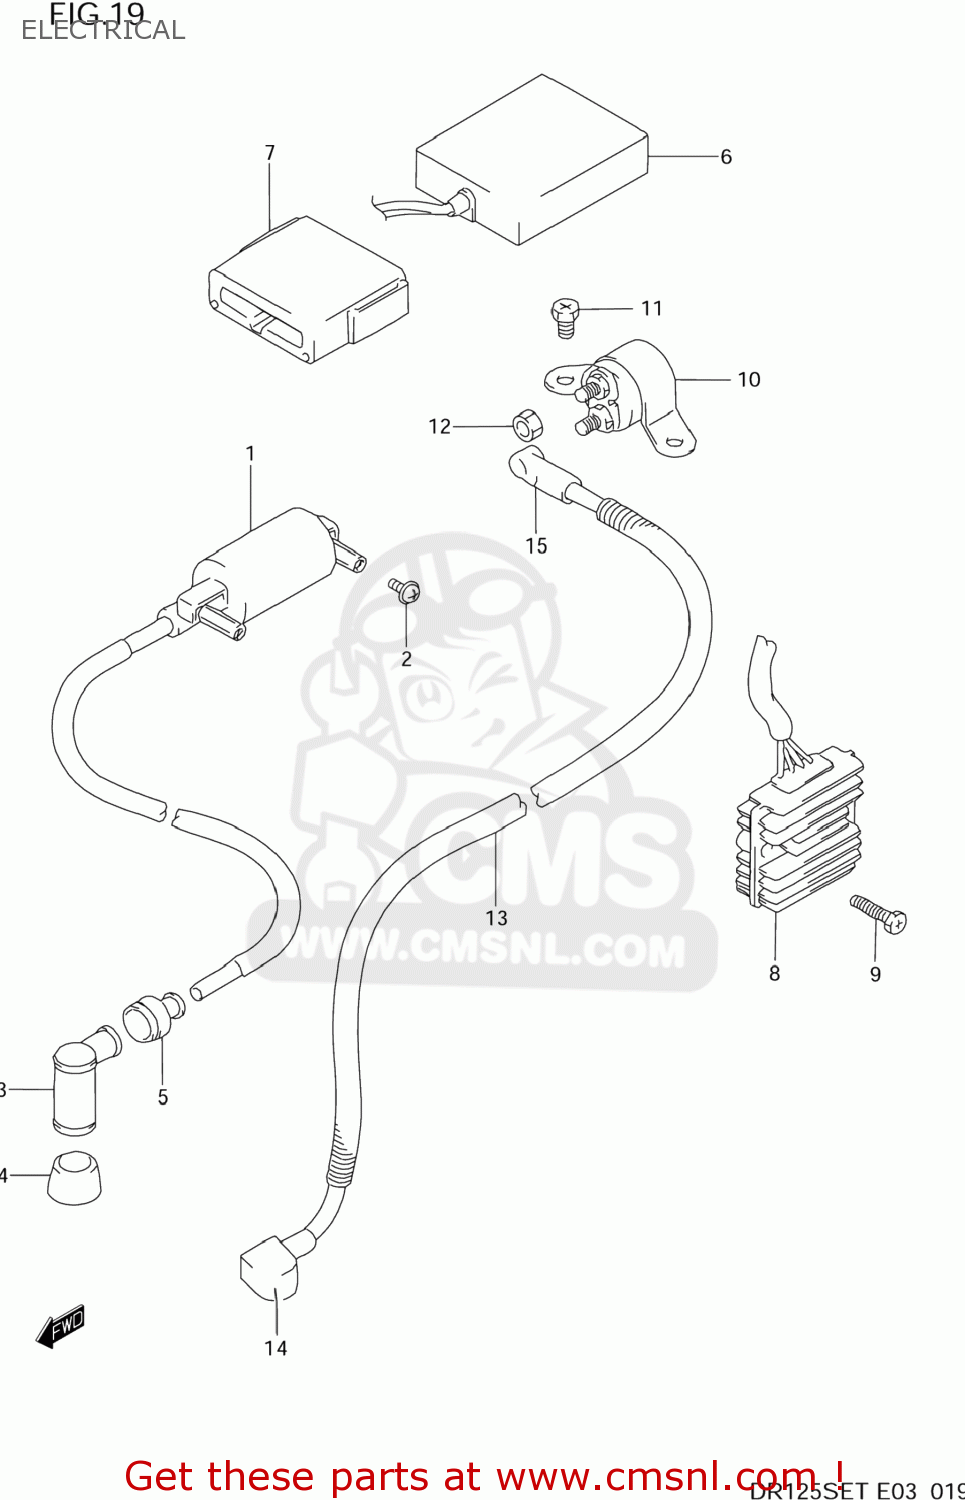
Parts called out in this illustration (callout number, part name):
1	COIL ASSY,IGNITION
2	SCREW
3	CAP ASSY,SPARK PLUG
4	SEAL,SPARK PLUG CAP
5	SEAL,HIGH TENSION CORD
6	CDI UNIT
7	CUSHION,CDI UNIT
8	RECTIFIER ASSY
9	SCREW (6X25)
10	RELAY ASSY,STARTING MOTOR
11	SCREW(6X10)
12	NUT
13	WIRE,STARTER MOTOR LEAD
14	CAP,STARTER MOTOR TERMINAL
15	CAP,STARTER RELAY
